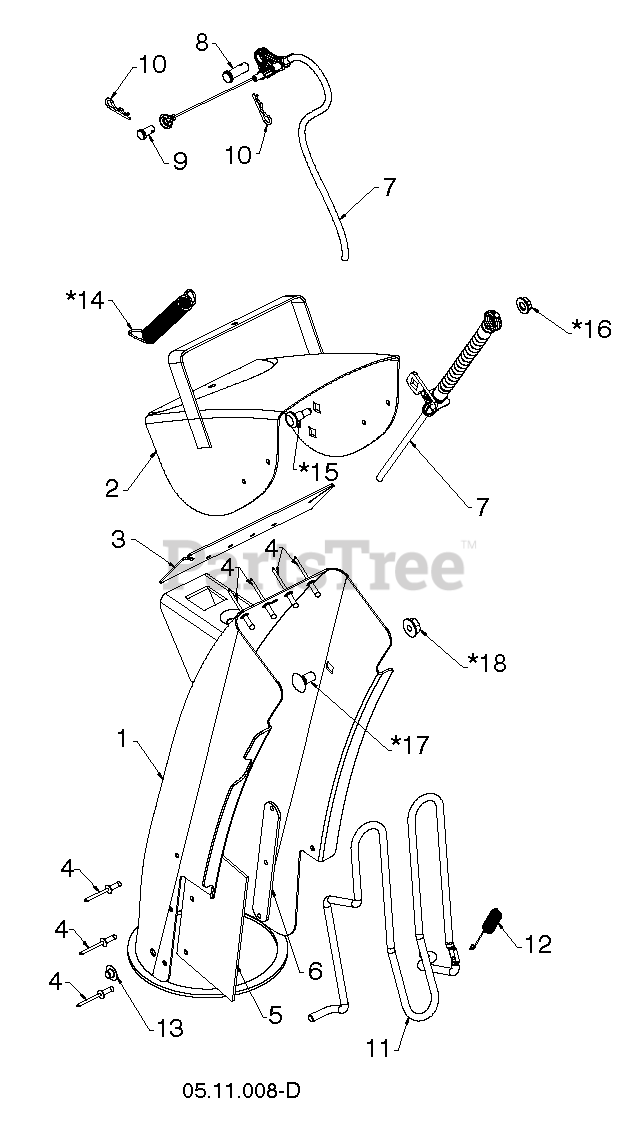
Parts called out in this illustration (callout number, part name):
1	ASM.CHUTE/DEFLECTOR.668
7	CABLE CONTROL.CHUTE.DEFL.BOWDE
8	PIN CLEVIS 5/16X.875
9	PIN CLEVIS .25 X .31
10	HAIRPIN.SOFT.ZINC.059X1.125
11	ROD.GUARD.CHUTE (2 2)
12	SPRING.CHUTE.GUARD
13	NUT
14	SPRING.DEFLECTOR.REM.CHUTE
15	BOLT CAR BLK 5/16-18 X 5/8
16	NUT.HEX.LRG.FLANGE.1/4-20.LOCK
17	BOLT CAR BLK 5/16-18 X 5/8
18	LOCKNUT-FLANGE 5/16-18
